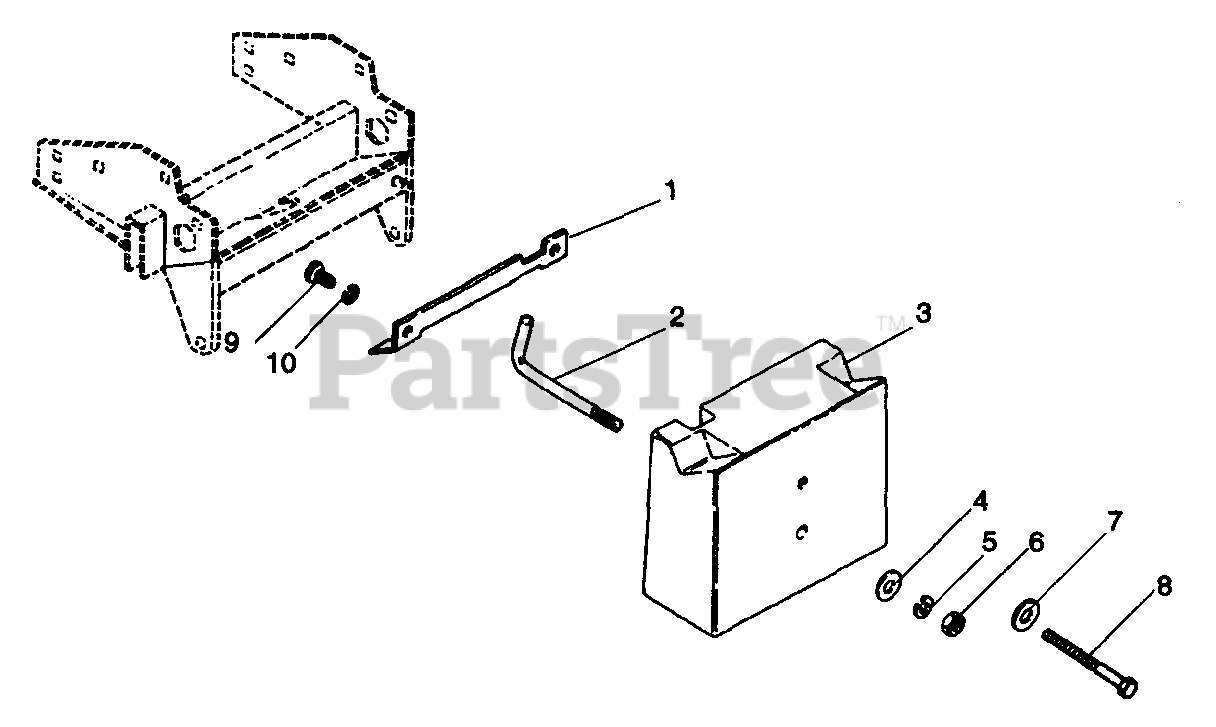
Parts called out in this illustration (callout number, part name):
1	HOOK BRACKET
2	HOOK ROD
3	COUNTER WEIGHT - HTH
4	WSHR-FL-STL .531X1.062X.095 PL
5	WSHR-LK .500X.151 HVY PL
6	NUT .50-13 PL
7	WSHR-FL-STL .382X.812X.062
8	BLT-HEX .38-16X5.50 YWZC
9	BLT-HEX .38-16X1.00 PL GR5
10	WSHR-LK .375X.115 HVY PL
